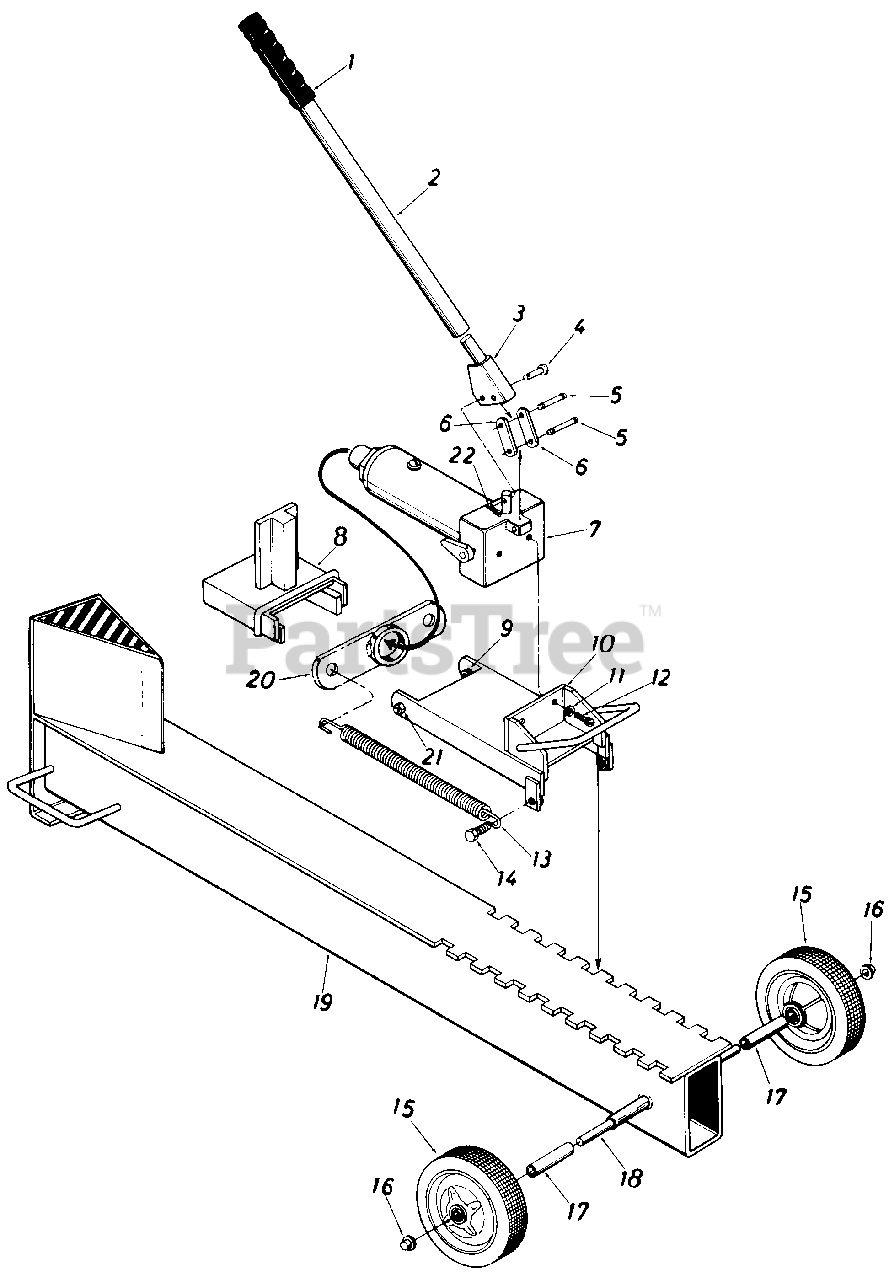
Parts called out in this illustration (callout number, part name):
1	Handle Grip
2	Handle 3/8" Dia. Rod
3	Handle Socket
4	Clevis Pin
5	Pin & Ring Assembly
7	Hydraulic Pump & Cyl inder
8	Push Plate Ass'y.
9	Socket Hd. Bolt 1/2-13 x .75" Lg.
10	Cylinder Mounting
11	L.-Wash. 3/8" I.D.
12	Socket Hd. Bolt 3/8-16 x . 75" Lg.
13	Extension Spring .75" O.D. x 10.75" Lg.
14	Hex L.-Bolt 3/8-16 x .75" Lg.
15	Wheel 7.0" x 1.75"
16	1/2" Push Cap
17	Spacer
18	Axle 1/2" Dia. x 12" Lg.
19	Tube and Rail Ass'y.
20	Cyl. Return Ass'y.
21	Hex Cent. L.-Nut 1/2-13 Thd.
22	Hair Pin Cotter
